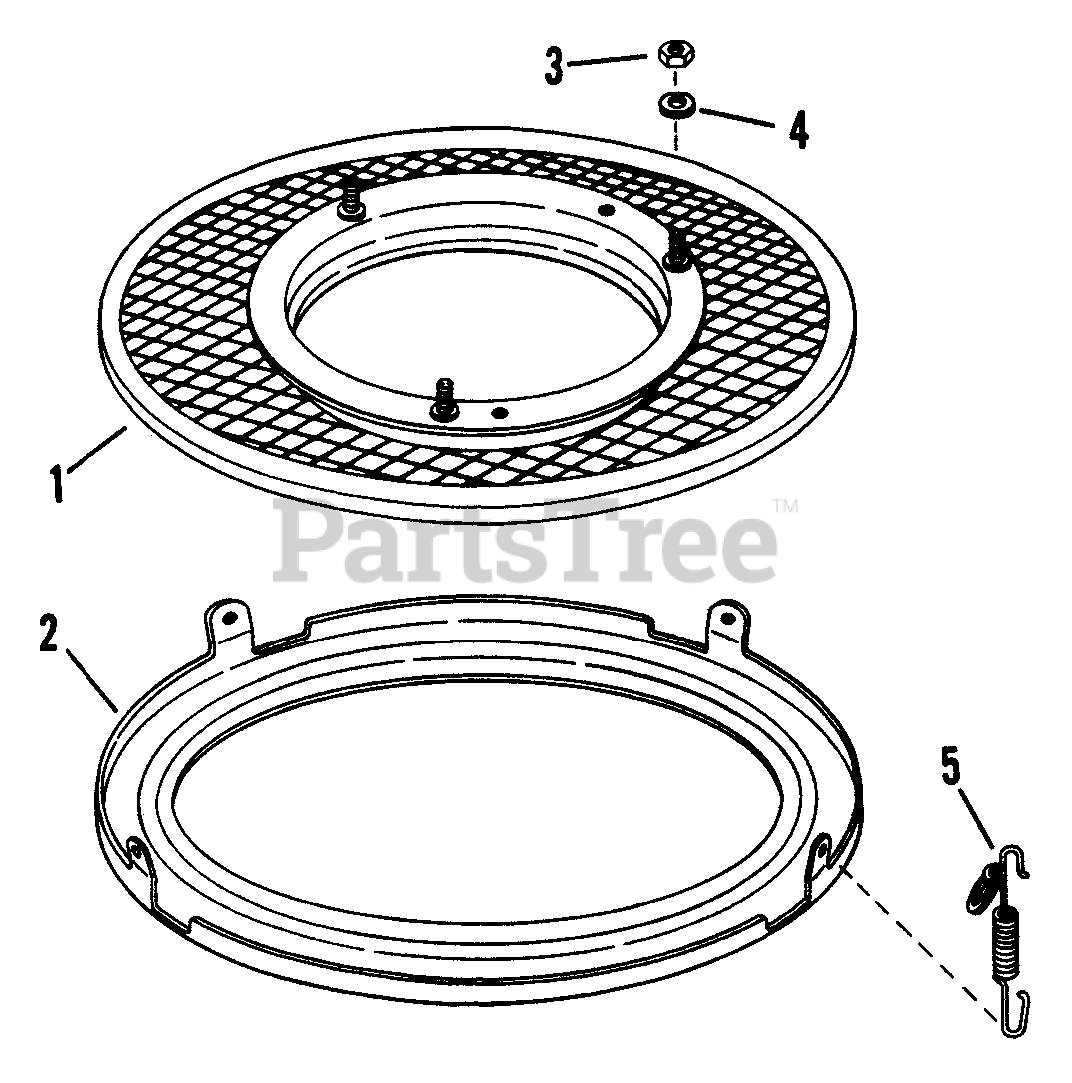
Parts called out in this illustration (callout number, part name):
1	SCREEN, Fastener Assembly
2	RING, Bottom
3	NUT, 5/16-24 Hex
4	WASHER, 5/16 Split Lock
5	SPRING
